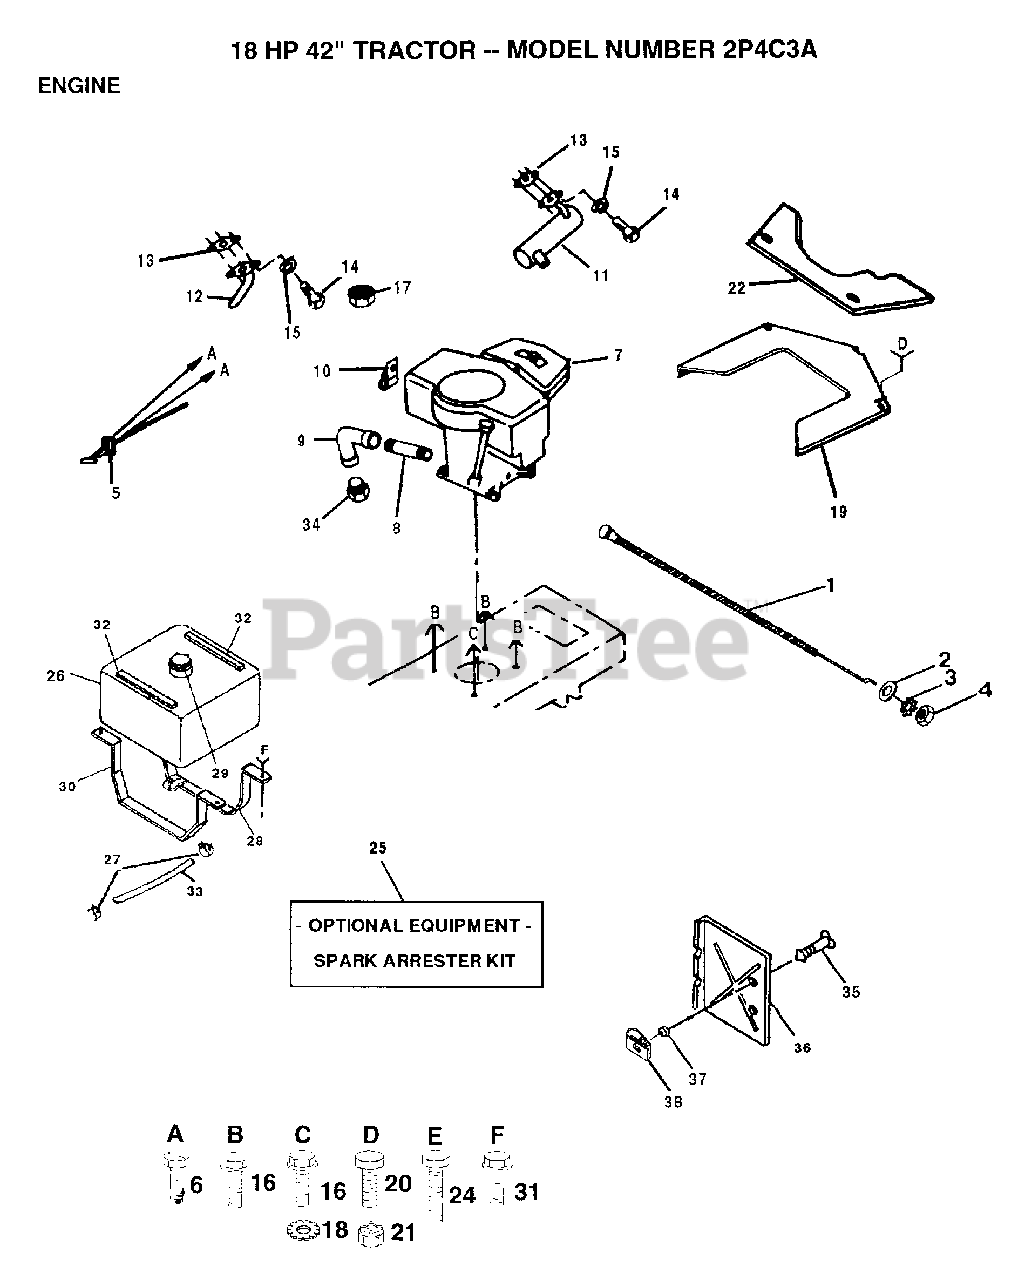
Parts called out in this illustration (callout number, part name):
1	CHOKE CONTROL
2	WASHER
3	LOCKWASHER
6	SCREW LT
8	PIPE NIPPLE LT
9	ELBOW
10	CLIP T
12	EXHAUST TUBE T
15	LOCKWASHER
16	SCREW LT
17	NUT
18	LOCKWASHER
19	SHIELD HEAT FRT
22	REAR BAFFLE T
25	SPARK ARREST KIT
27	HOSE CLAMP
28	STRAP ASM. F.TANK
30	"STRAP,TANK"
31	SCREW LT
32	"STRIP,FORM"
33	FUEL LINE T
35	STUD.1/4.TURN
36	HEAT SHIELD
37	RETAINER LT
38	RECEPTACLE LT
